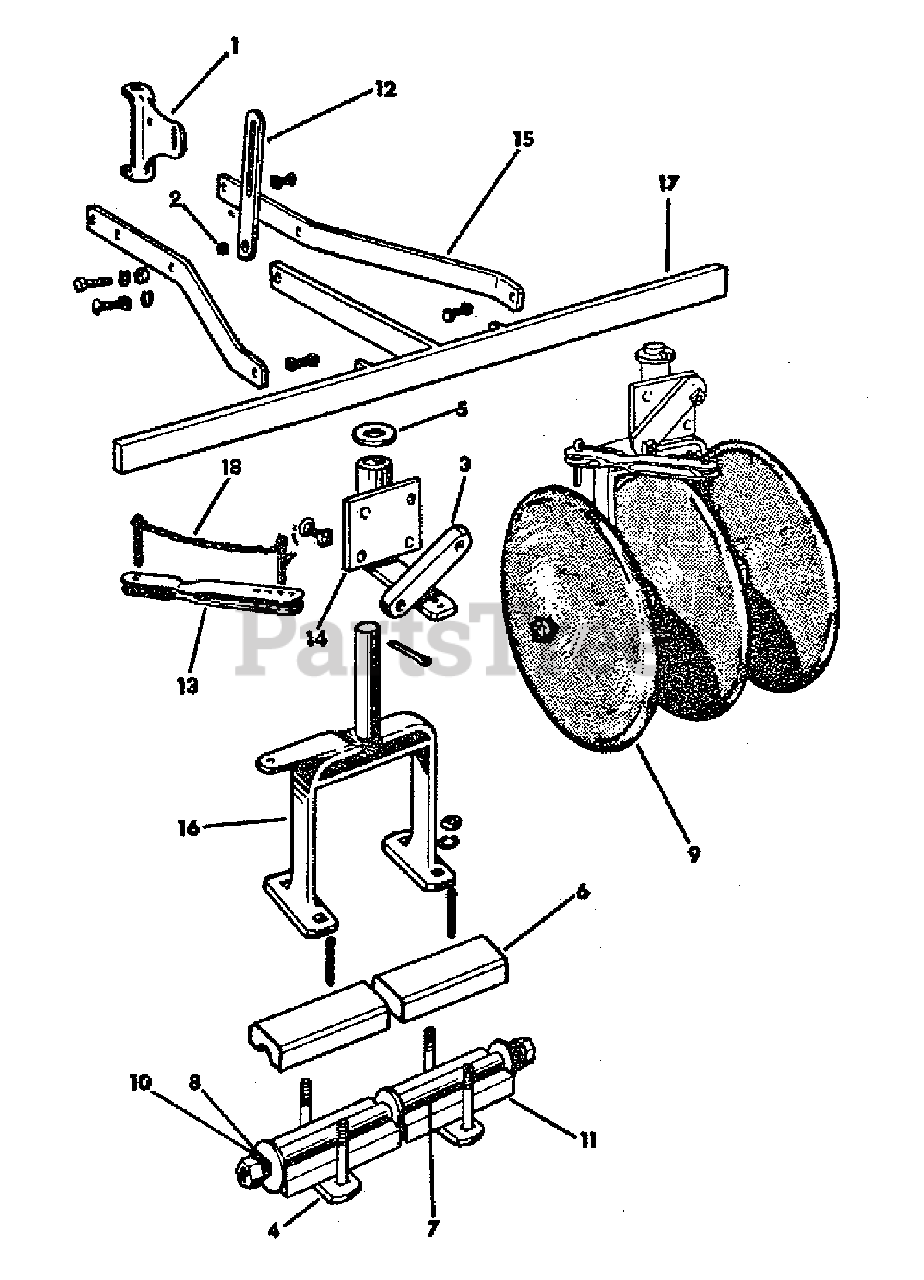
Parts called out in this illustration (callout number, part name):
1	END, Draw Bar
2	SPACER, Adjustment Link
3	CLIP, Clamp
4	CLIP, Bearing
5	WASHER, Post
6	BLOCK, Upper Bearing
7	SPACER, Disc
8	AXLE, 8 Disc
9	BLADE, 12" Disc
10	AXLE, 6 Disc
11	BLOCK, Lower Bearing
12	LINK, Tilt Adjusting
13	STRAP ASSEMBLY, Angle Adjusting
14	CLAMP ASSEMBLY
16	ARCH ASSEMBLY
17	CROSS BAR ASSEMBLY
